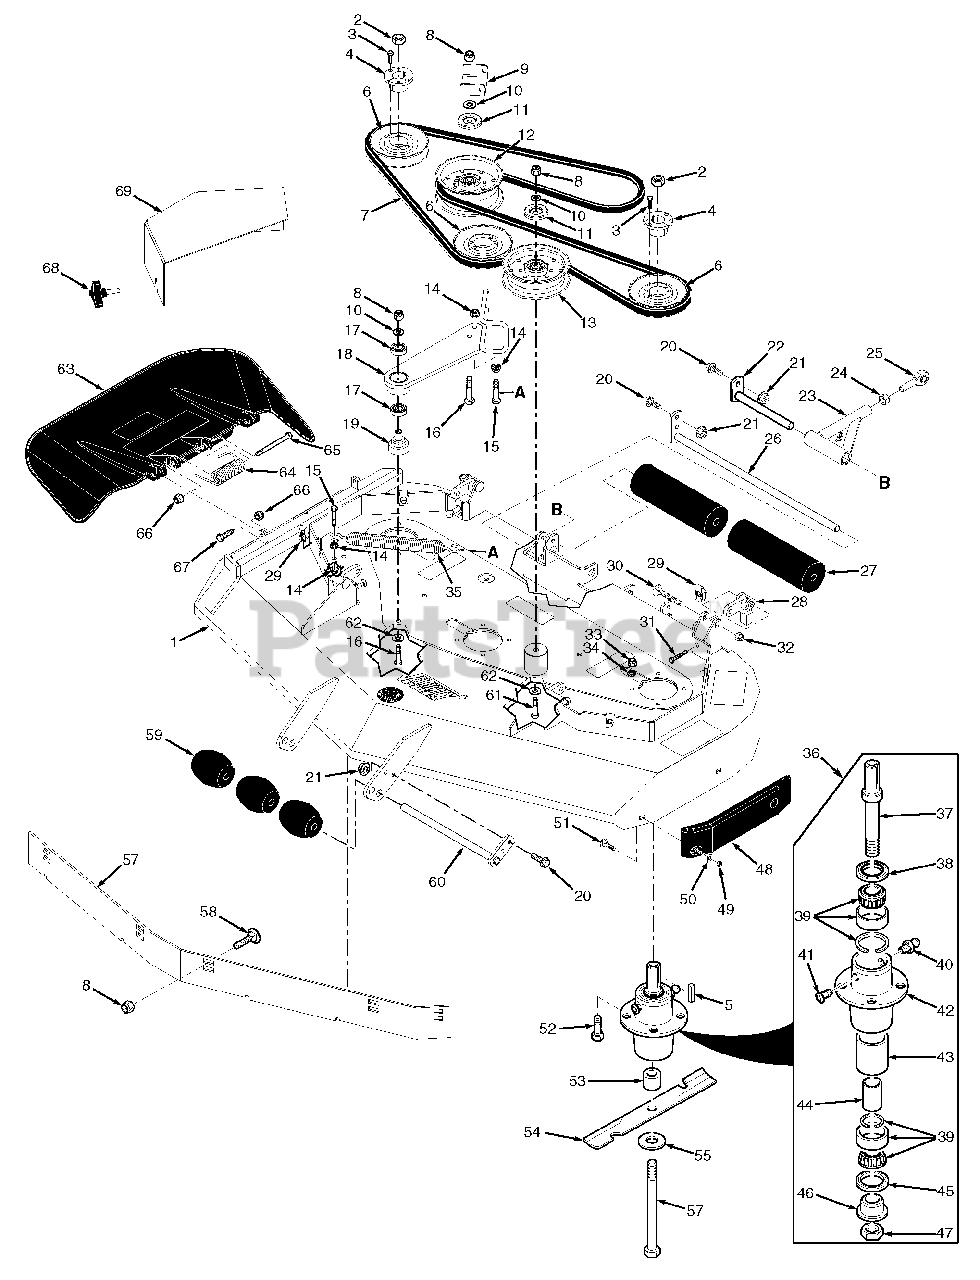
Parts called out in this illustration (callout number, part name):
1	Cutter Deck w/Decals (48V)
2	Nut, 5/8-11 UNC
3	Bolt, Hex Head 1/4-20 x 1"
4	Tapered Hub
5	Key, 1/4 x 1/4 x 1"
6	Pulley, 5.13 OD (48V)
7	Belt, Cutter Deck (48V)
8	Nut, Elastic Stop 3/8-16
9	Bracket, Belt Guide
10	Flatwasher, 3/8-.391 x .938 x .105 HD
11	Dust Shield
12	Pulley, 5" Idler
13	Pulley, 5" Idler
14	Nut, Serrated Flange 3/8-16
15	Bolt, Hex Head 3/8-16 x 1-1/2" Gr.8
16	Bolt, Hex Head 3/8-16 x 3-1/4"
17	Bearing
18	Idler Arm Assembly - 48V
19	Pivot, Idler
20	Bolt, Hex Head 5/16-18 x 1"
21	Nut, Serrated Flange 5/16-18
22	Shaft Weldment, Pusharm Mount
23	Pusharm Assembly, LH
24	Nut, 1/2-20 UNF
25	Rod End, 1/2-20 RH
26	Shaft Weldment
27	Guide Roller
28	Lever, Deck Level
29	U-Nut, 3/8-16
30	Bolt, Carriage 7/16-14
31	Bolt, Hex Head 3/8-16 x 2" Special
32	Nut, Elastic Stop 7/16-14
33	Nut, Elastic Stop 5/16-18
34	Lockwasher, 5/16" Spring
35	Spring, Cutter Deck
36	Spindle Assembly
37	Shaft, Spindle
38	Seal, Upper
39	Bearing Assembly
40	Grease Fitting
41	Valve Grease Relief
42	Housing, Spindle
43	Spacer, Outside
44	Spacer, Inside
45	Seal, Lower
46	Bushing, Lower
47	Nut, Special 1-1/16" - 18
48	Pad, Deck Wear
49	Nut, Center Lock 5/16-18
50	Flatwasher, 5/16-.344 x .688 x .065
51	Bolt, Carriage 5/16-18 x 3/4"
52	Bolt, Hex Head 5/16-18 x 1-3/4"
53	Spacer, Spindle Bottom
54	Cutter Blade, 16-1/2" (48V)
55	Flatwasher, 5/8-.688 x 1.75 x .134 HD
56	Bolt, Hex Head 5/8-11 x 9-1/2"
57	Baffle, Flange 48V
58	Bolt, Carriage 3/8-16 x 1"
59	Wheel Anti-Scalp
60	Shaft Weldment
61	Bolt, Carriage 3/8-16 x 5"
62	Flatwasher, 3/8-.406 x 2.25 x .1875
63	Discharge Chute Assembly - 48V
64	Spring, Discharge Chute
65	Bolt, Hex Head 5/16-18 x 4-3/4"
66	Nut, Elastic Stop 5/16-18
67	Bolt, Hex Head 5/16-18 x 1-3/4"
68	Knob w/Stud
69	Belt Cover, RH (48V)
